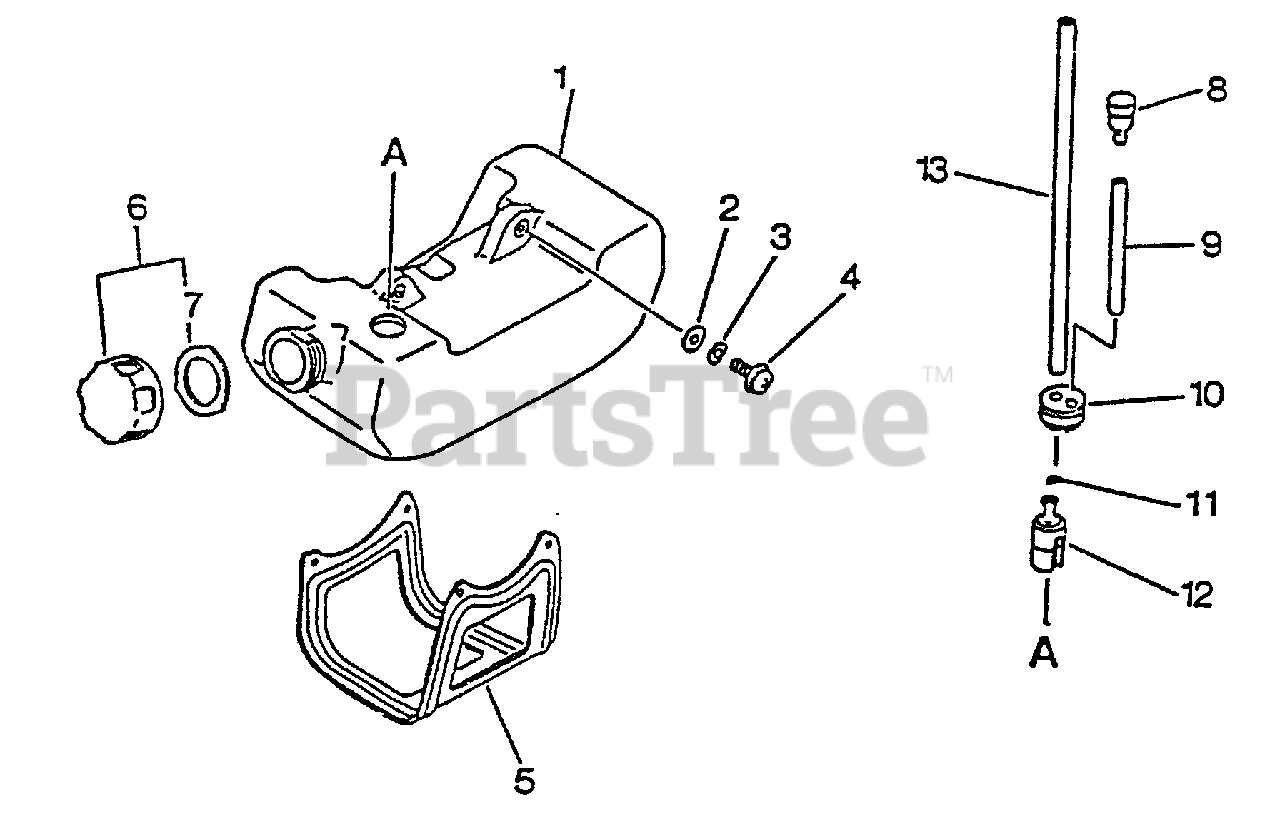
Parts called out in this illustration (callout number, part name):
1	TANK, FUEL
2	WASHER - 5
3	LOCKWASHER - 5
4	SCREW - 5X16
5	GUARD, FUEL TANK
6	CAP ASSY
7	GASKET, CAP
8	VENT, FUEL TANK
9	PIPE - 3X5X70 -- BLACK
10	GROMMET
11	CLIP - 6
12	FILTER, FUEL
13	PIPE - 3X5X180 -- BLACK
